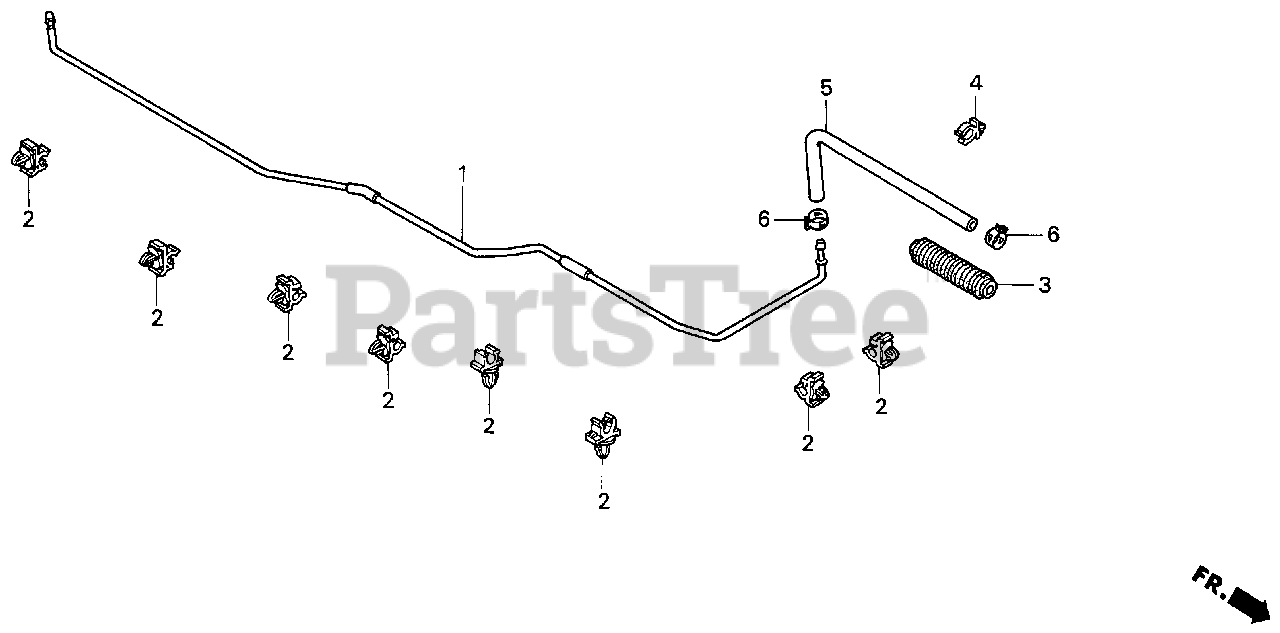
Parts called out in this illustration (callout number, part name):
1	PIPE, FUEL FEED
2	CLAMP, FUEL VENT PIPE
3	TUBE C, CORRUGATED
4	CLIP A, FUEL HOSE
5	BULK HOSE, FUEL (4.5X3000) (4.5X360)
6	CLIP, TUBE (D8.5)
